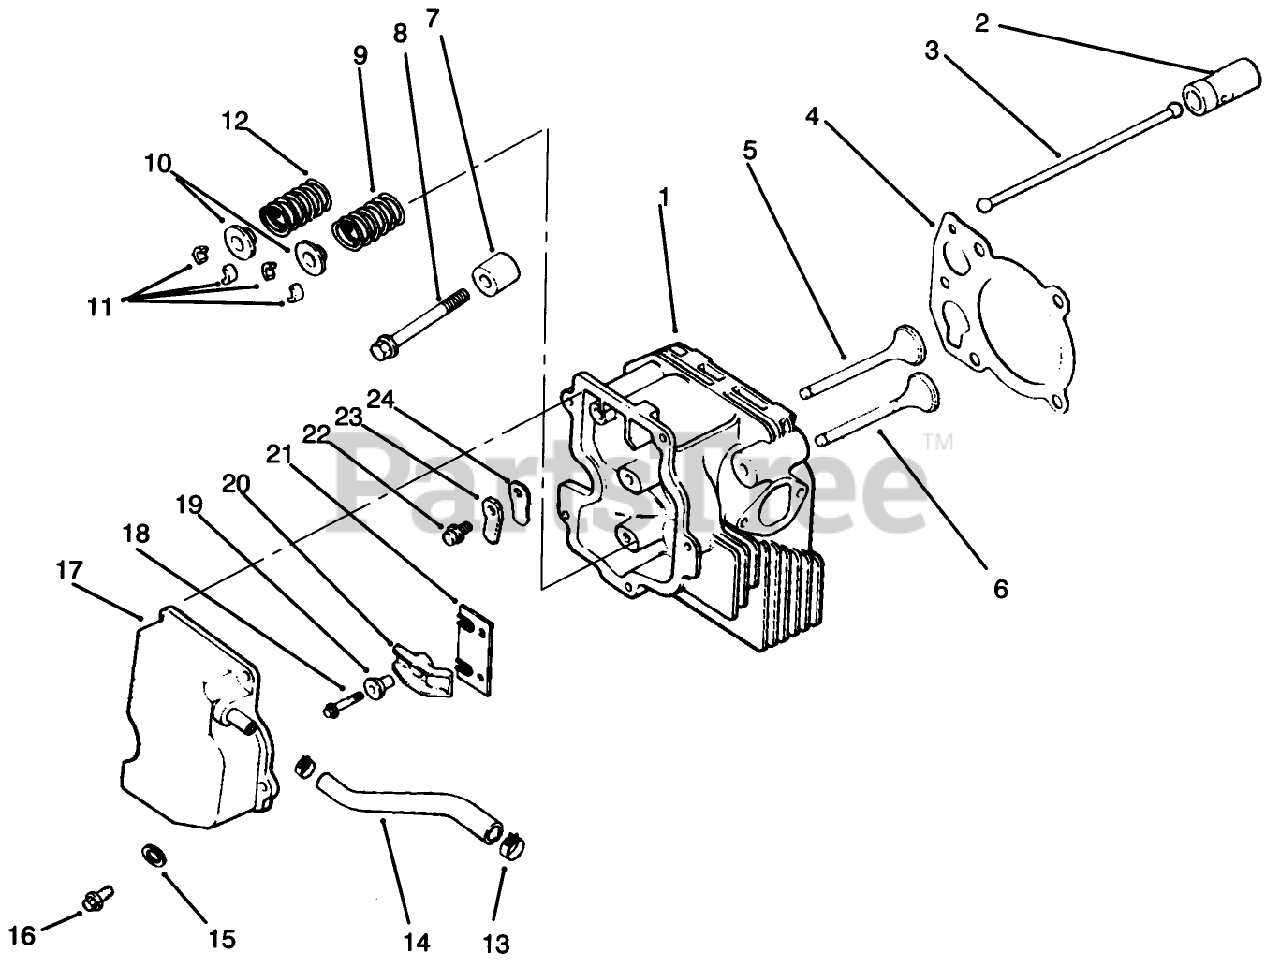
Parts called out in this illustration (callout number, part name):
1	Cylinder Head (Only On: 72042,72043,72062,72063)
2	Lifter-Valve
3	Rod-Push (Only On: 72042,72043,72062,72063)
4	Gasket-Cylinder Head (Only On: 72042, 72063, 72062, 72043)
5	Valve-Intake STD (Only On: 72042, 72063, 72062, 72043)
5	Valve-Intake .25 (Only On: 72042,72043,72062,72063)
6	Valve-Exhaust STD (Only On: 72042,72043,72062,72063)
6	Valve-Exhaust .25 (Only On: 72042, 72063, 72062, 72043)
7	Spacer-Head Bolt Exhaust (Only On: 72042, 72063, 72062, 72043)
8	Screw M10x1.5x80 (Only On: 72042, 72063, 72062, 72043)
9	Spring-Valve Exhaust (Only On: 72042,72043,72062,72063)
10	Cap-Valve Spring
11	Kit-Retainer
12	Spring-Valve Intake (Only On: 72042, 72063, 72062, 72043)
13	Clamp
14	Hose-Breather (Only On: 72042, 72063, 72062, 72043)
15	Washer-Flat (Only On: 72042, 72063, 72062, 72043)
17	Cover-Valve W/Nipple (Only On: 72042, 72063, 72062, 72043)
19	Ball-Rocker Pivot
20	Arm-Rocker
21	Plate-Guide (Only On: 72042, 72063, 72062, 72043)
23	Retainer-Reed
